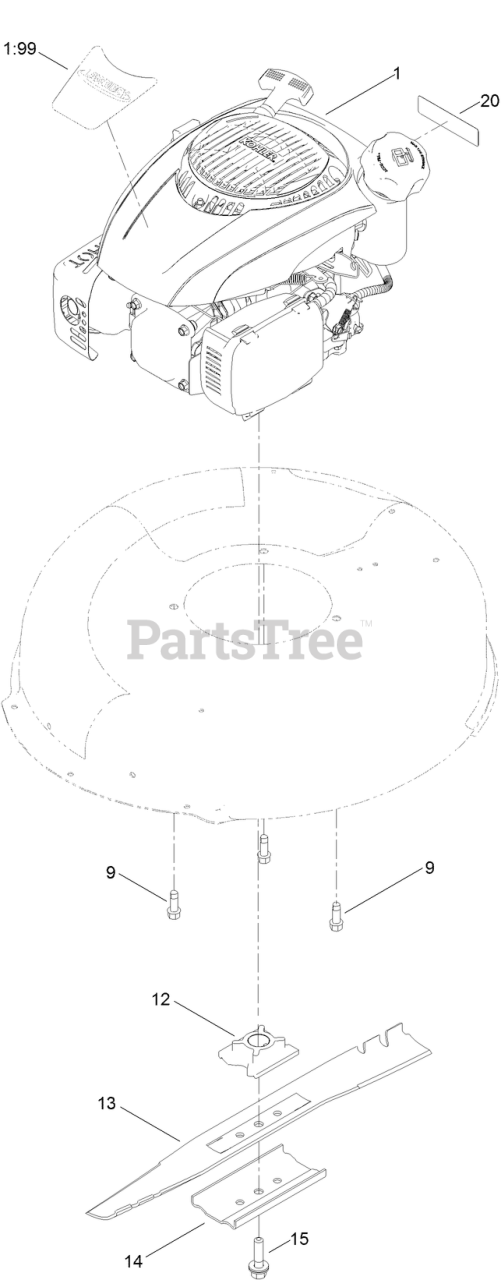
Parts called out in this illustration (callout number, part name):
1:99	DECAL-SHROUD
9	SCREW-TAPTITE
12	RETAINER-BLADE
14	SUPPORT-BLADE
15	BOLT-BLADE
20	DECAL-ARRESTOR, SPARK
